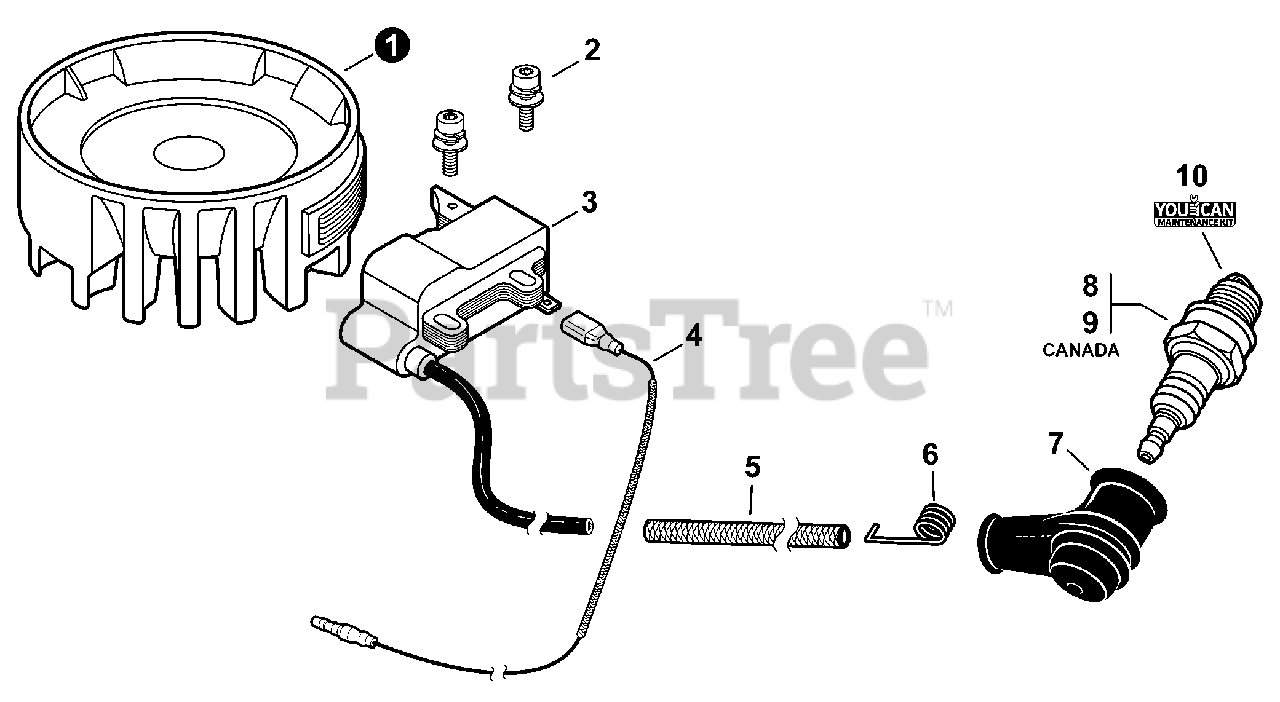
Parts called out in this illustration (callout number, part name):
1	FLYWHEEL
2	BOLT 4×20
3	COIL, IGNITION
4	LEAD - IGNITION
5	TUBE, INSULATOR 7×8.6×55
6	TERMINAL, SPARK PLUG
7	CAP, SPARK PLUG
8	SPARK PLUG - BPM8Y
9	SPARK PLUG - BPMR8Y
10	TUNE-UP KIT - YOUCANT
